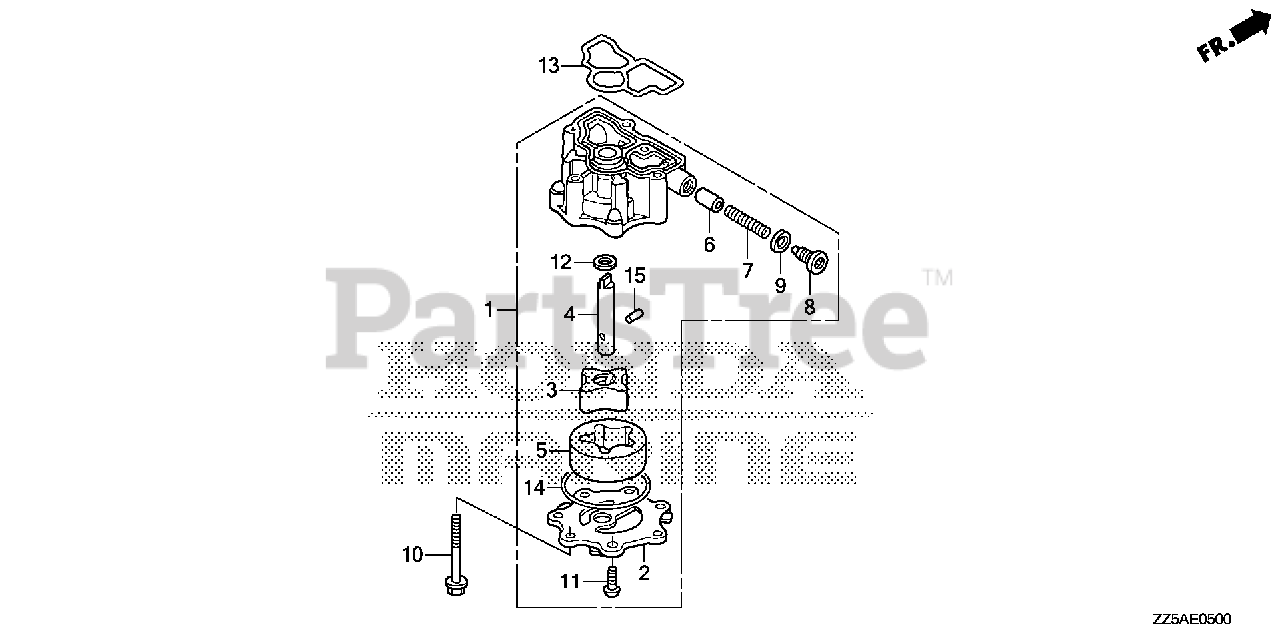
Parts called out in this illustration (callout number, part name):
1	PUMP ASSY., OIL
2	COVER, OIL PUMP
3	ROTOR (INNER)
4	SHAFT, OIL PUMP
5	ROTOR A (OUTER)
10	BOLT, FLANGE (6X55)
11	SCREW, PAN (6X16)
12	WASHER, THRUST (13MM)
13	O-RING, PUMP COVER
14	O-RING (54X2.4) (ARAI)
15	ROLLER (5X17.8)
